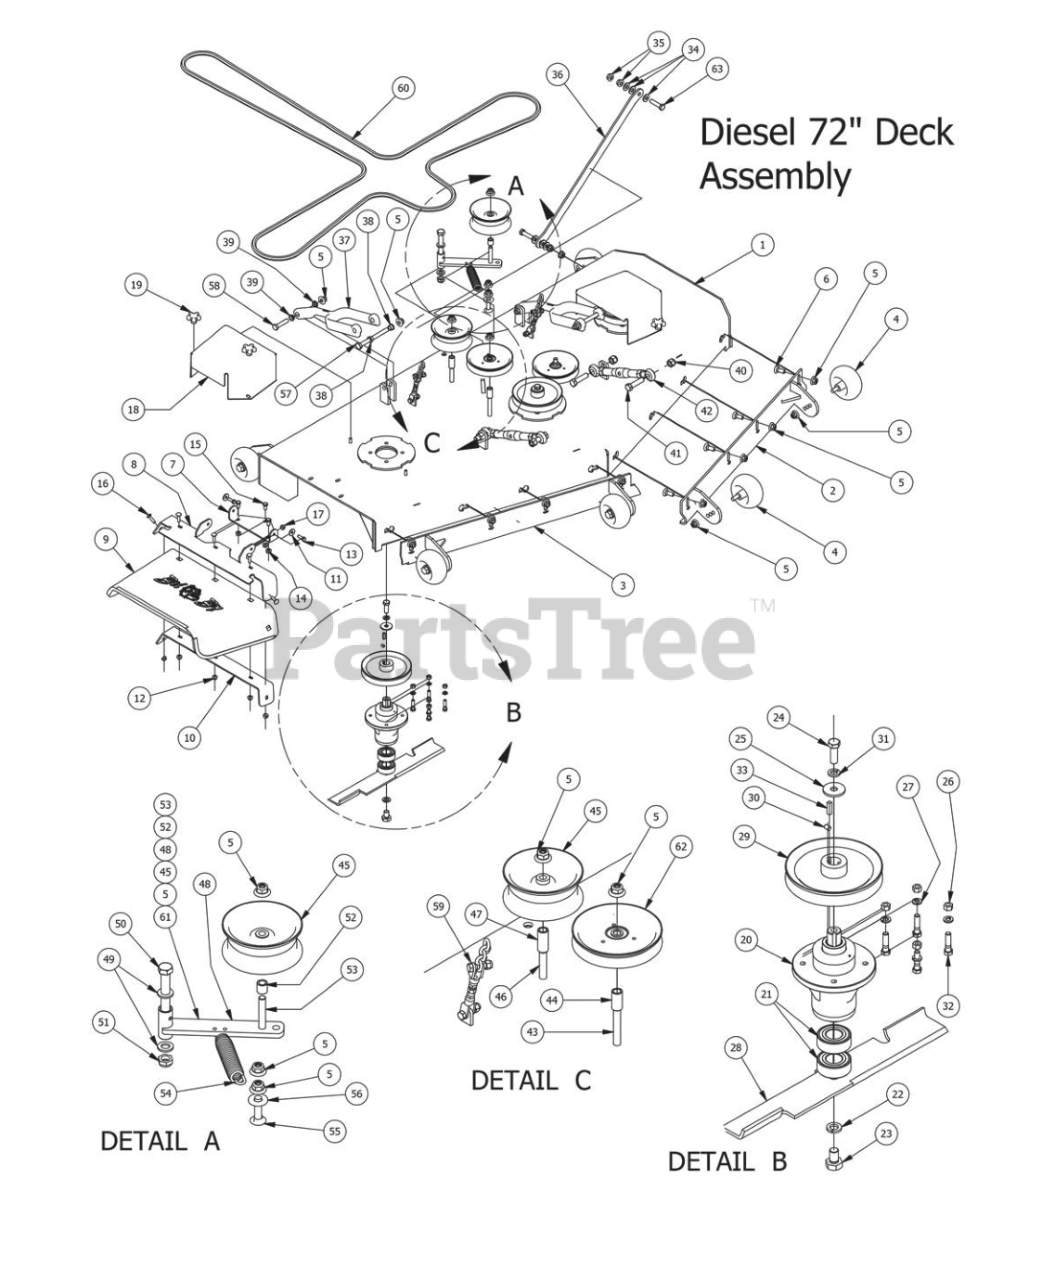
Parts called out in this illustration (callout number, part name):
1	72" Deck - Shell Only
2	72" Deck Adjustable Front (Left)
3	72" Deck Adustable Front (Right)
4	Deck Wheel
5	1/2-13 Nylon Flange Nut-Orange
6	1/2" x 1 1/4 Carriage Bolt
7	Discharge Chute Hanger (deck mounted)
8	60" Discharge Chute Upper Hanger
9	Rubber Discharge Chute
10	60" Discharge Lower Bracket
11	.360 ID Plastic Washer
12	5/16" Flange Nut Zinc W/Serrations
13	5/16" x 1" Bolt
14	3/8" Flange Nut
15	3/8" x 3/4" Hex Bolt
16	5/16" x 1 1/4" Carriage Bolt
17	5/16" Nylon Flange Nut
18	72 Spindle Cover
19	5/16" Knob
20	Double Bearing Spindle
21	Double Bearing for spindle
22	5/8" Lock Washer
23	5/8" x 1 1/2" Grade 8 Bolt
24	1/2"-20 x 1 1/2 - Grade 5 Fine Thread Bolt
25	1/2 Belleville Washer
26	3/8-16 Hex Nuts Zinc
27	3/8 Lockwasher Zinc
28	72" High Lift Fusion Blade
29	7" Deck Pulley
30	5/16 Set Screw
31	1/2" Lock Washer
32	3/8" x 1 1/2" Hex Bolt
33	1/4" x 1" Key
34	.505 Nylon Spacer
35	1/2" Flange Nut
36	72" Diesel Deck Panhard Linkage Bar
37	Deck Arm Assembly
38	Flange Bushing For Deck Arm upper
39	Flange for Lower Deck Arm
40	5/8 Std NC Nylock Nut
41	5/8" x 2 1/2" Hex Bolt
42	Turnbuckle (Top Link)
43	1/2 x 3 1/2 Flange Bolt Grade 8
44	.502 ID X.75 OD X 1.500 Leng
45	5 3/4" Deck Idler Pulley
46	1/2" x 4" Bolt (Grade 8)
47	1 3/4" Pulley Spacer
48	Deck Idler
49	.635 ID Plastic Washer
50	5/8" x 4" Hex Bolt
51	5/8-11 Nylon Insert Jam Half Nut
52	3/4 OD x 1/2 ID x 3\4 Length
53	1/2-13 x GR 5 Hex Bolt Zinc
54	2009 Deck/Pump Idler Spring
55	1/2 x 2" Carriage Bolt
56	1/2" Flat Washer
57	1/2" x 5 1/2" Bolt
58	1/2-13X 2-1/4 GR Hex Bolts
59	5- Link Adjustable Deck Hange
60	B252-50 Fits 72 Diesel
61	Deck Idler Assy Componets 5,45,48,52,53
62	5-3/4 Idler Pulley 72" Decks only
63	1/2-13x2 Grade 8 Hex Bolt
